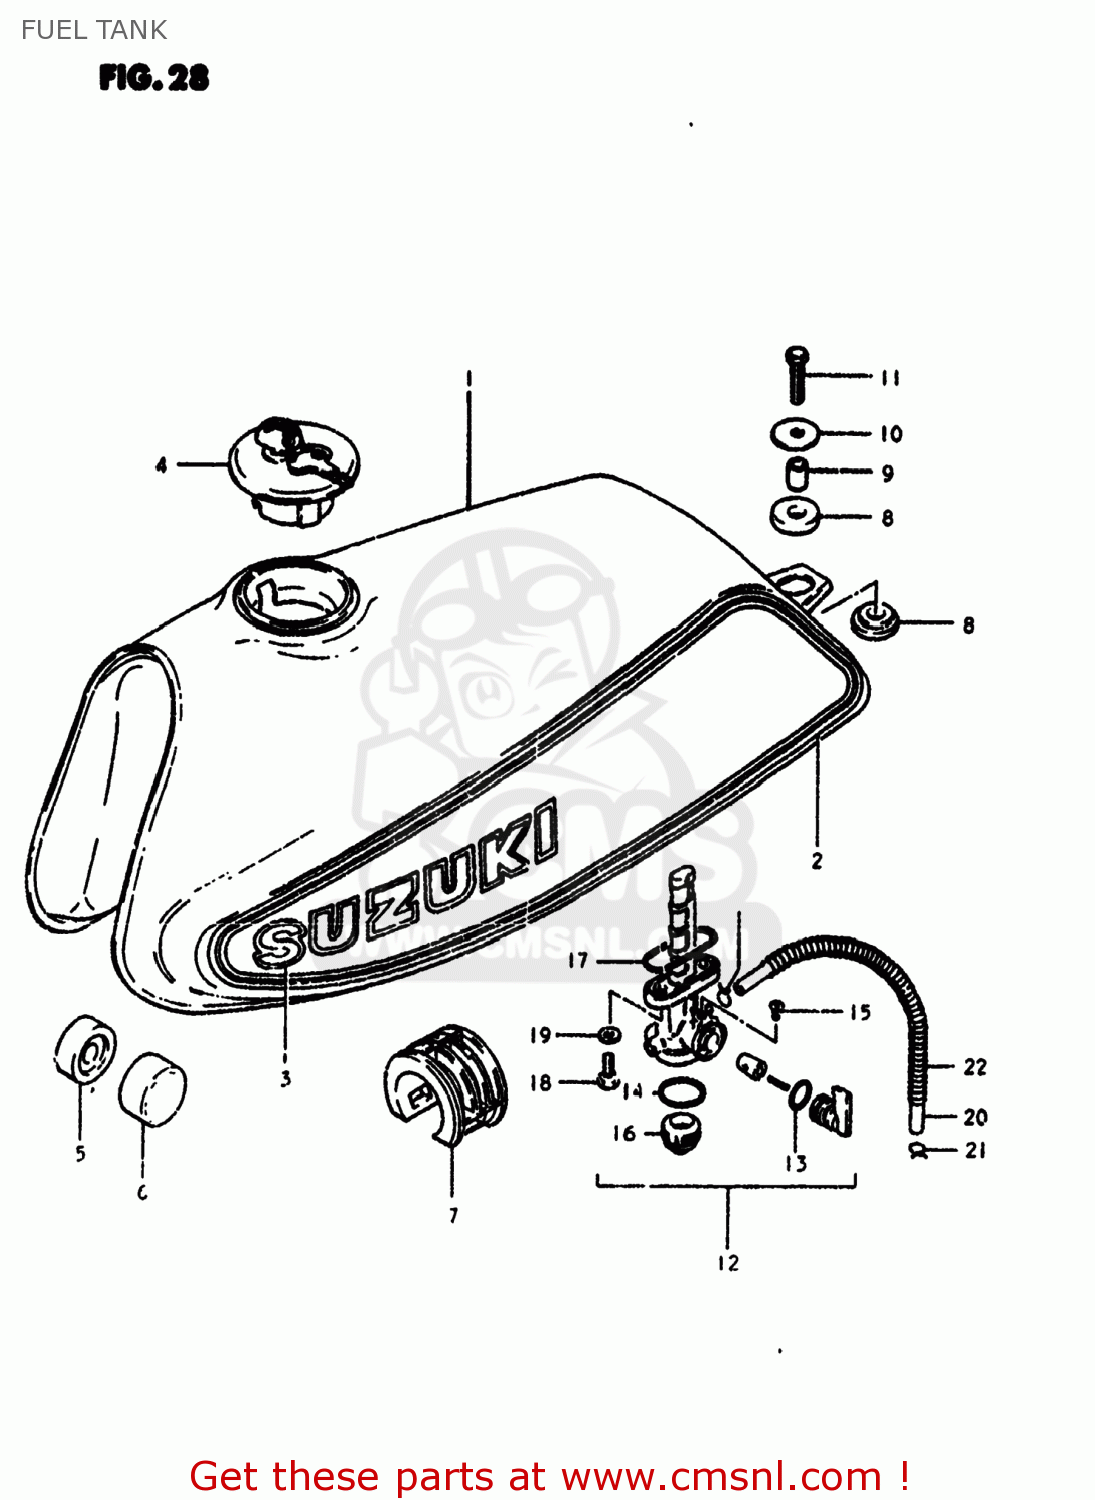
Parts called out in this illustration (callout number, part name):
1	TANK ASSEMBLY,FUEL
2	TAPE SET,FUEL TANK
3	EMBLEM,FUEL TANK(WHITE)
4	CAP SET,FUEL TANK
5	CUSHION
6	CUSHION
7	CUSHION,FUEL TANK
8	BUSH(12X15X20)
9	SPACER (8X12X15)
10	WASHER (8.5X29X1.6)
11	BOLT
12	COCK ASSEMBLY,FUEL
13	O-RING
14	GASKET,FILTER (NAS)
15	SCREW,FUEL COCK LEVER
16	CUP,STRAINER
17	O RING,FUEL COCK
18	BOLT(6X20)
19	GASKET
20	HOSE
21	CLIP
22	SPRING
